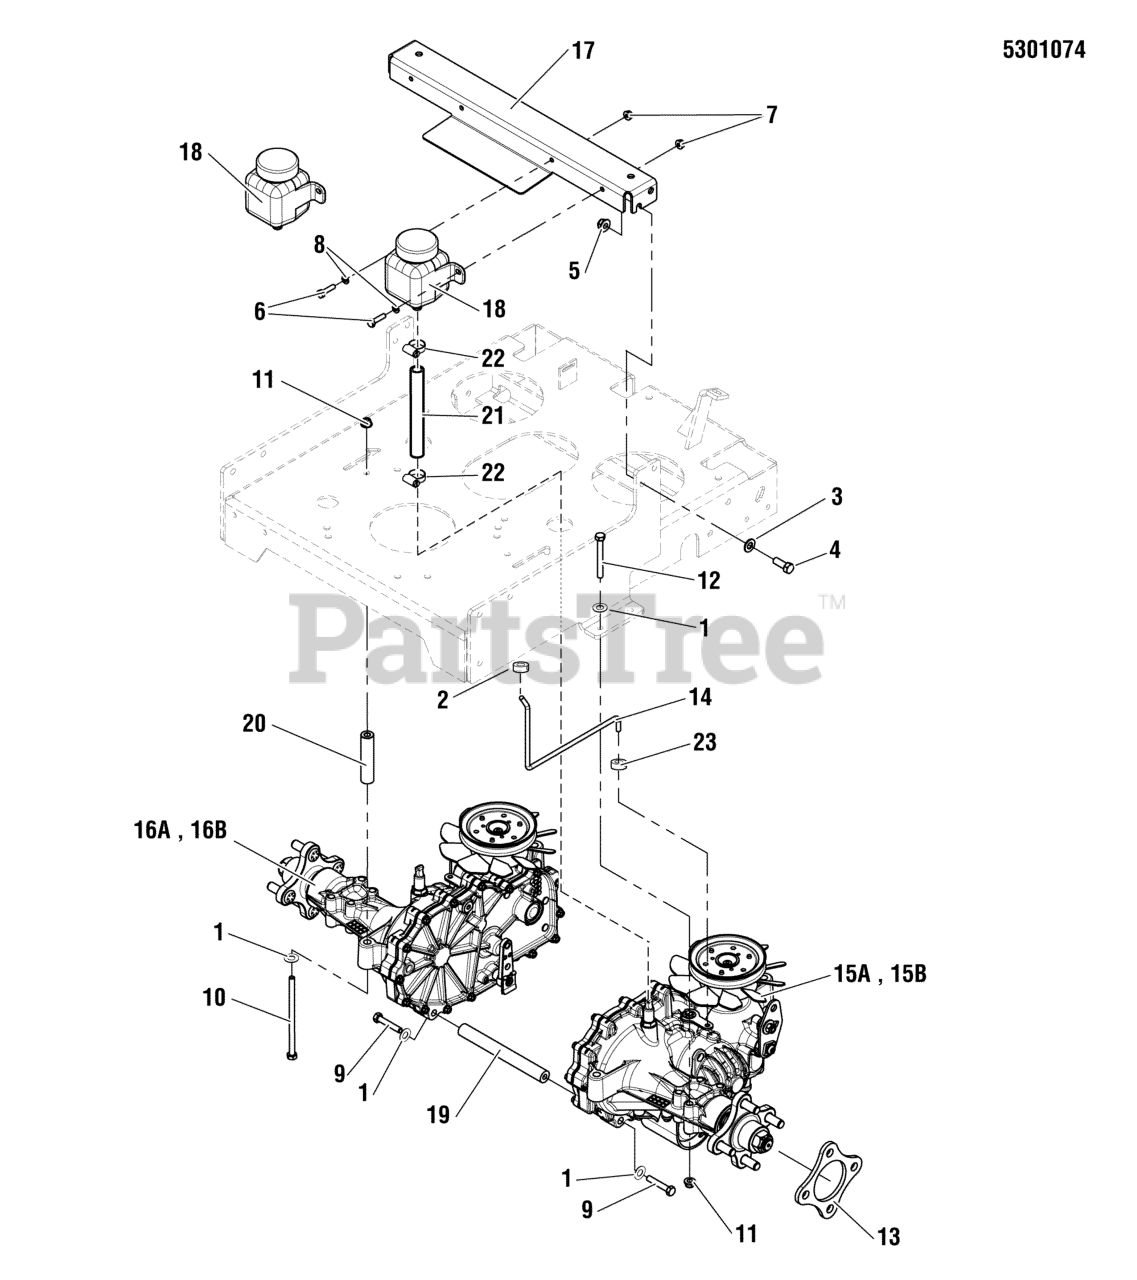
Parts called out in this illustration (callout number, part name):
1	WASHER, 5/16 GD.9 FLAT
2	COLLAR, 5/16 SET
3	WASHER, 3/8 SAE
4	BOLT, 3/8-16 X 1" GD5 CZ
5	NUT, 3/8-16 HEX NYLOCK FLANGE
6	BOLT, 1/4-20 X 3/4", GD5
7	NUT, 1/4-20 HEX NYLOCK FLANGE
8	WASHER, 1/4 SAE
9	BOLT, 5/16-18 X 2-1/4 GD5 YZ
10	BOLT, 5/16-18 X 5-1/2, GD 5, YZ
11	NUT, 5/16-18 HEX NYLOCK FLANGE
12	BOLT, 5/16-18 X 2-3/4, GD 5, YZ
14	ROD, HYDRO RELEASE, SW20
15A	TRANSMISSION, ZT2800, LH (ZH-GMBB-3A5A-1KLX)
15B	TRANSMISSION, ZT3100, LH (ZJ-GMFE-3B5B-1RLX)
16A	TRANSMISSION, ZT2800, RH (ZH-KMBB-3A5A-1KLX)
16B	TRANSMISSION, ZT3100, RH (ZJ-KMFE-3B5C-1RLX)
17	PLATE, HYD TANK MOUNT - RED
18	RESERVOIR, HYDRO OIL, 350 ML
19	ROD, HYDRO LINK, CZ
20	SPACER, .34 X .75 X 3.27, YZ
21	HOSE, 1/2" X 4.25 PUSH-ON
22	CLAMP, HOSE, .75 FREE DIA.
23	COLLAR, 1/4" SET
